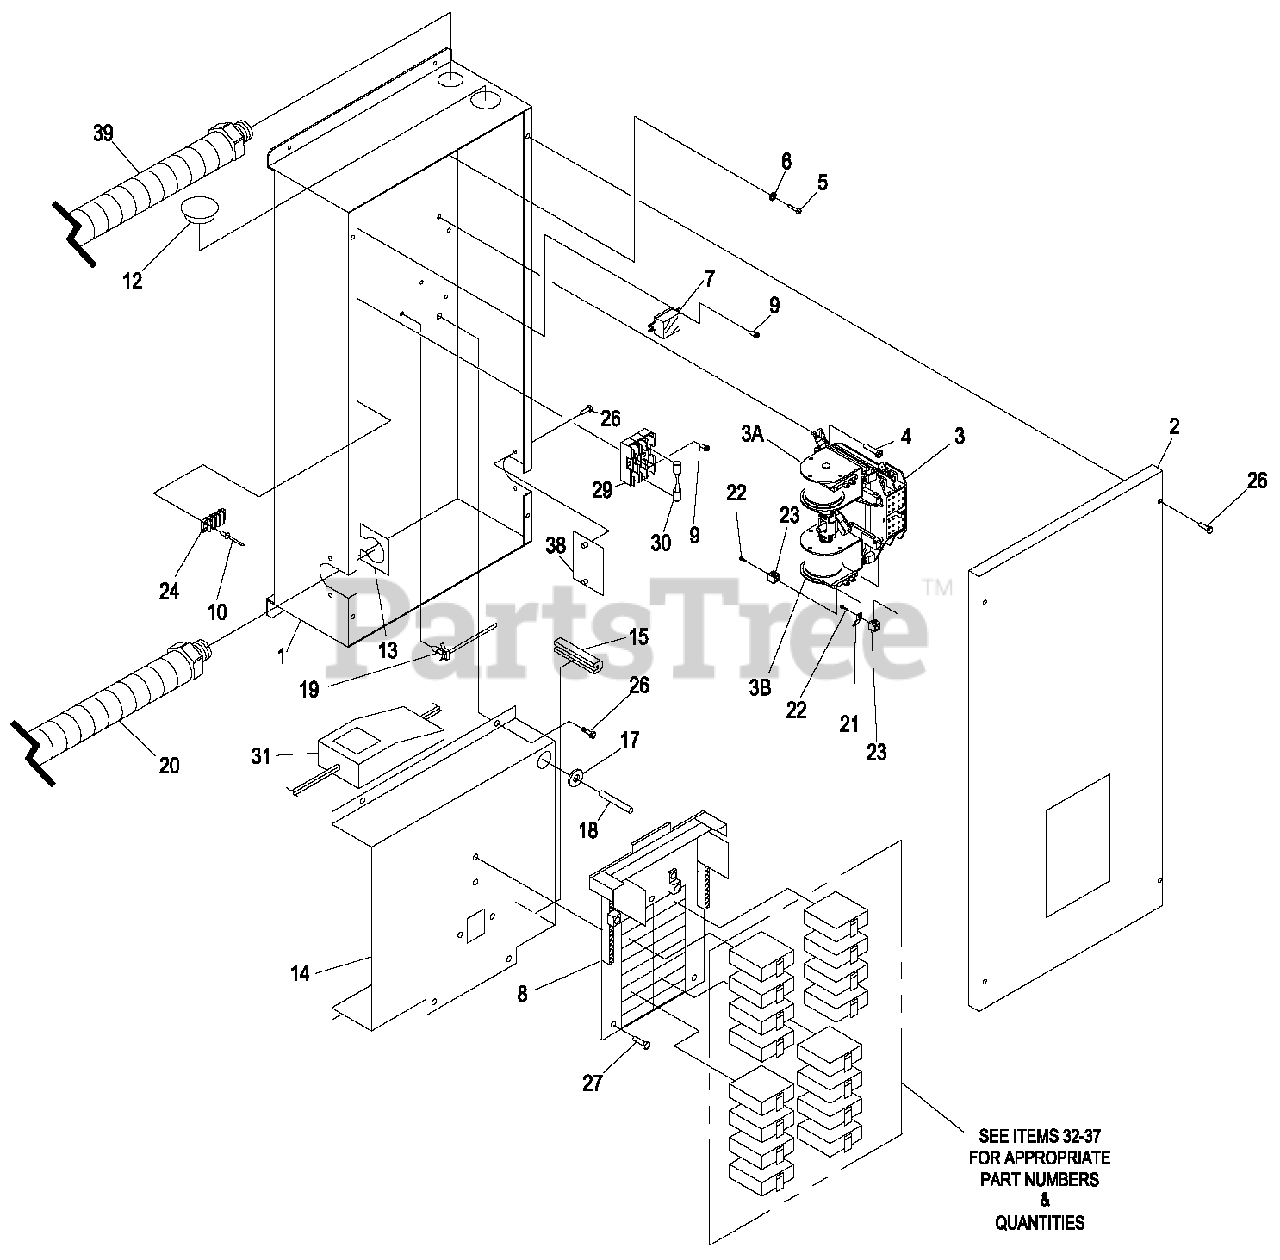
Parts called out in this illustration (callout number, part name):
1	GTS LOAD CENTER ENCLOSURE GRAY
2	COVER 8 POS GTS LOAD CTR GRAY
3	TRANSFER SWITCH HOME STANDBY 100A 2P 250V
3A	COIL UTILITY
3B	COIL STANDBY
4	SCREW HHTT M5-0.8 X 10
5	SCREW TAPTITE 1/4-20 X 5/8
6	LOCK WASHER, SPECIAL-1/4"
7	RELAY PANEL 12VDC DPDT 10A@240VAC
8	8CIR L/CNTR 125A/240V
9	SCREW HHTT M4-0.7 X 10
10	RIVET POP .156" X .675"
12	PLUG PLASTIC
13	HARNESS ADAPTER PLATE GRAY
14	SUBPLATE GTS LOAD CENTER GRAY
15	U-CHANNEL
17	GROMMET 3/8 X 1/16 X 1/4
18	ARM EXTENDER PIN
19	CABLE TIE SELF MOUNTING 4.3LG
20	HARN GTS. MAN PNL 8CIR W/NEUT
21	LUG QUICK DISCONNECT NI-S 10X45 DEG BRASS / TIN
22	SCREW PPHM # 10-32X5/16 SEMS SC
23	LUG SLDLSS 1/0-# 14X9/16 AL/CU
24	BLOCK TERM 20A 6 X 3 X 1100V
26	SCREW SW 1/4"-20 X 5/8" WITH WASHER
27	SCREW HHTT M5-0.8 X 16 (8, 10, 12, 14, 16 CIRCUIT)
29	FUSEBLOCK 30A 600V 3POS W/SQ
30	FUSE 5A
31	BATTERY CHARGER ASSY
32	CIR BRKR 20A 2P
33	CIR BRKR 30A 2P
34	CIR BRKR 15A 1P
35	CIR BRKR 20A 1P
36	CIR BRKR 40A 2P
37	CIR BRKR 50A 2P
38	HARNESS ENTRY COVER GRAY
39	HARN GTS-EXT CONN BOX 8KW
